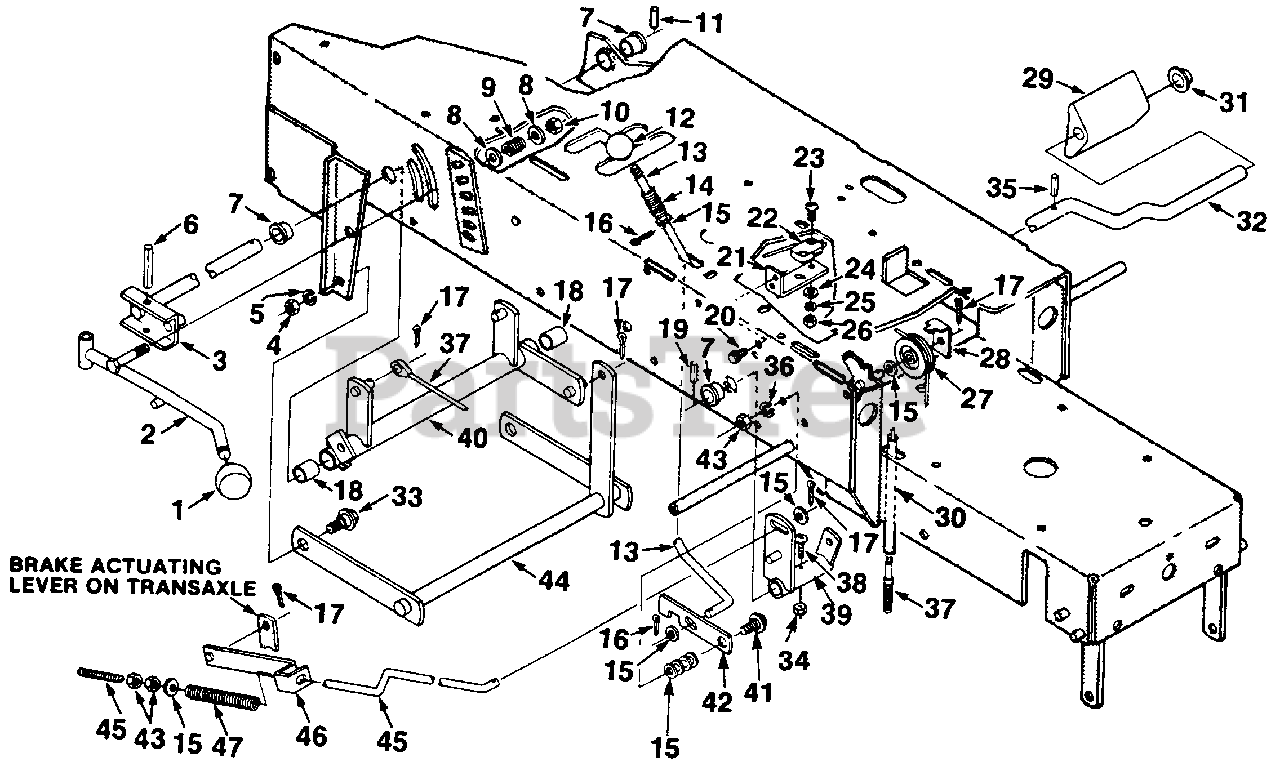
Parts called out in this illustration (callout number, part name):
1	KNOB- Implement lift handle
2	HANDLE- Lift
3	LIFT HANDLE BRACKET & ROD ASSY
4	NUT- Hex (3/8-16)
5	WASHER- Lock hvy (3/8")
6	PIN- Groove (5/16 x 2 1/4")
7	BUSHING- Flange
8	WASHER- Flat (3/8")
9	SPRING- Compression
10	NUT- Hex centerlock (5/16-18)
11	PIN- Spring (3/16 x 1")
12	KNOB- Parking brake
13	ROD- Brake lock
14	SPRING- Compression
15	WASHER- Flat (5/16")
16	PIN- Cotter (1/8 x 3/4")
17	PIN- Cotter (3/32 x 3/4")
18	BUSHING- Pivot
19	PIN- Roll (3/16 x 1")
20	BOLT- (1/4-14 x .44)
21	BRACKET- Safety switch
22	SWITCH- Safety
23	SCREW- Slotted truss head (#4-40 x 1.00)
24	WASHER- Flat (#4)
25	WASHER- Lock Reg (#4)
26	NUT- Hex (#4-40)
27	PULLEY- Lift cable
28	RETAINER- Lift cable
29	PEDAL- Clutch
30	TUBE- Cable cover
31	NUT- Push on (5/8")
32	ROD- Clutch
33	BOLT- Shoulder
34	NUT- Ctr lock (#10-24)
35	PIN- Roll
36	WASHER- Lock hvy. (5/16")
37	CABLE- Deck lift
38	SCREW- (10-24 x 1 3/4")
39	CLUTCH ROD ACTUATOR ASSY.
40	REAR LIFT & BUSHING ASSY.
41	BOLT- Idler pivot
42	LATCH- Parking brake
43	NUT- Hex (5/16-18)
44	REAR LIFT BAR ASSY
45	ROD- Brake
46	BRAKE SPRING BRACKET ASSY.
47	SPRING- Brake compression
